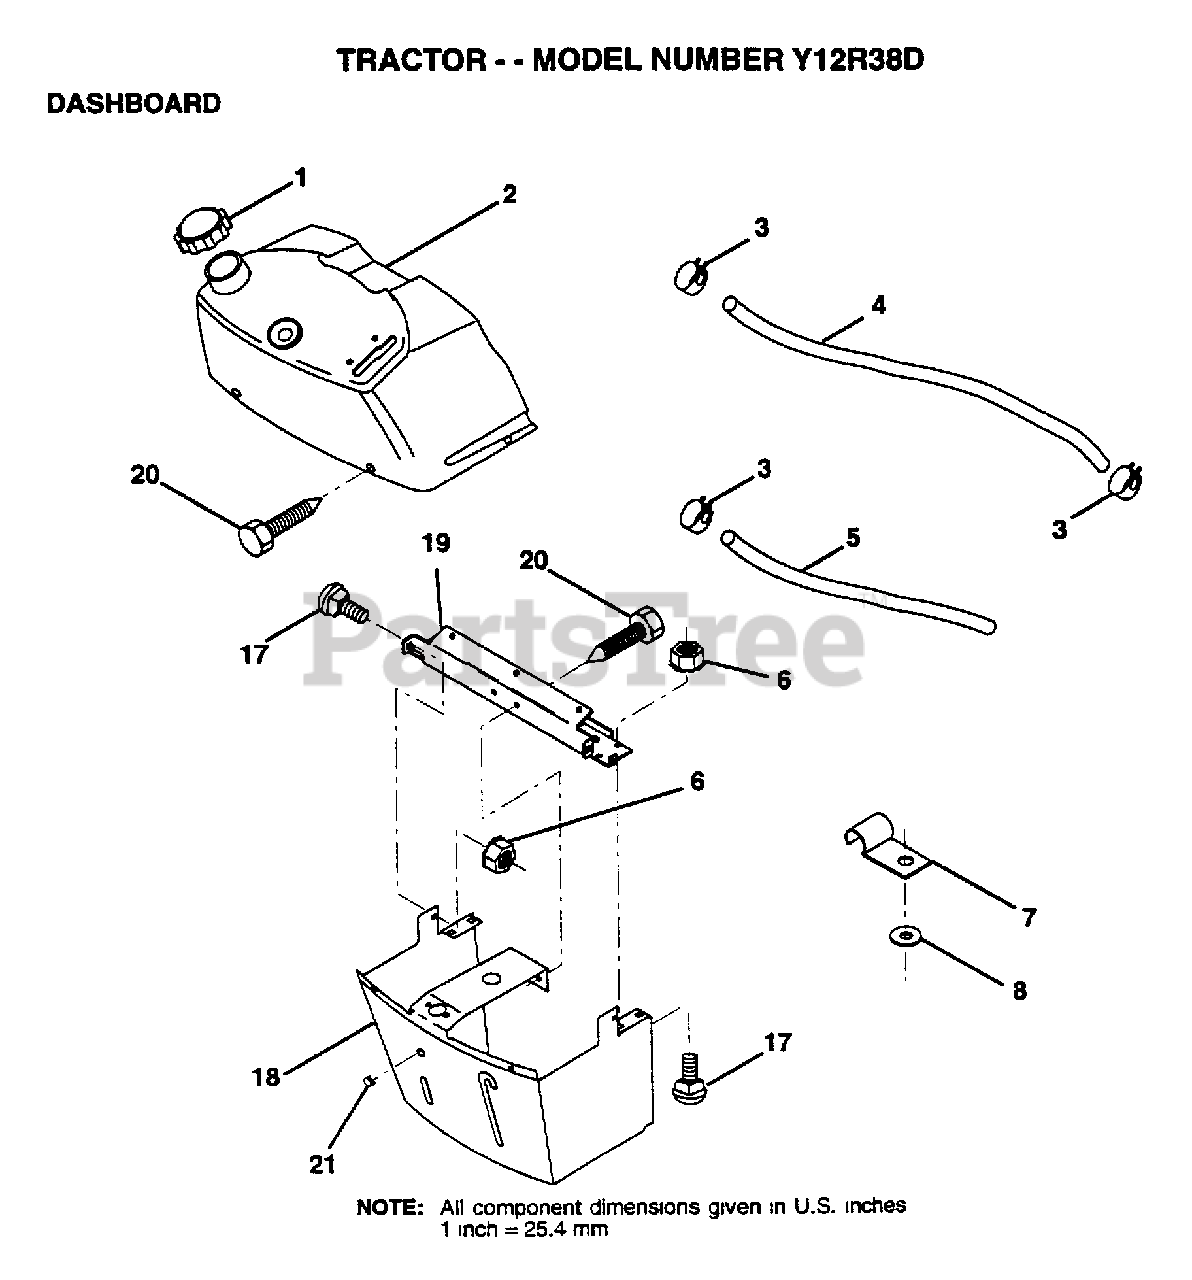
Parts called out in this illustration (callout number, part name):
1	CAP BLK FUEL LR
2	TANK.ASM.DASH.LR
3	HOSE CLAMP
5	FUEL LINE T
6	NUT HXKEP 1/4X20
7	CLIP T
8	WASHER PM
17	BOLT
18	SUPT ASM DASH
19	CROSS BRACE
20	SCREW.1/4-20X1/2
21	PLUG DOME
